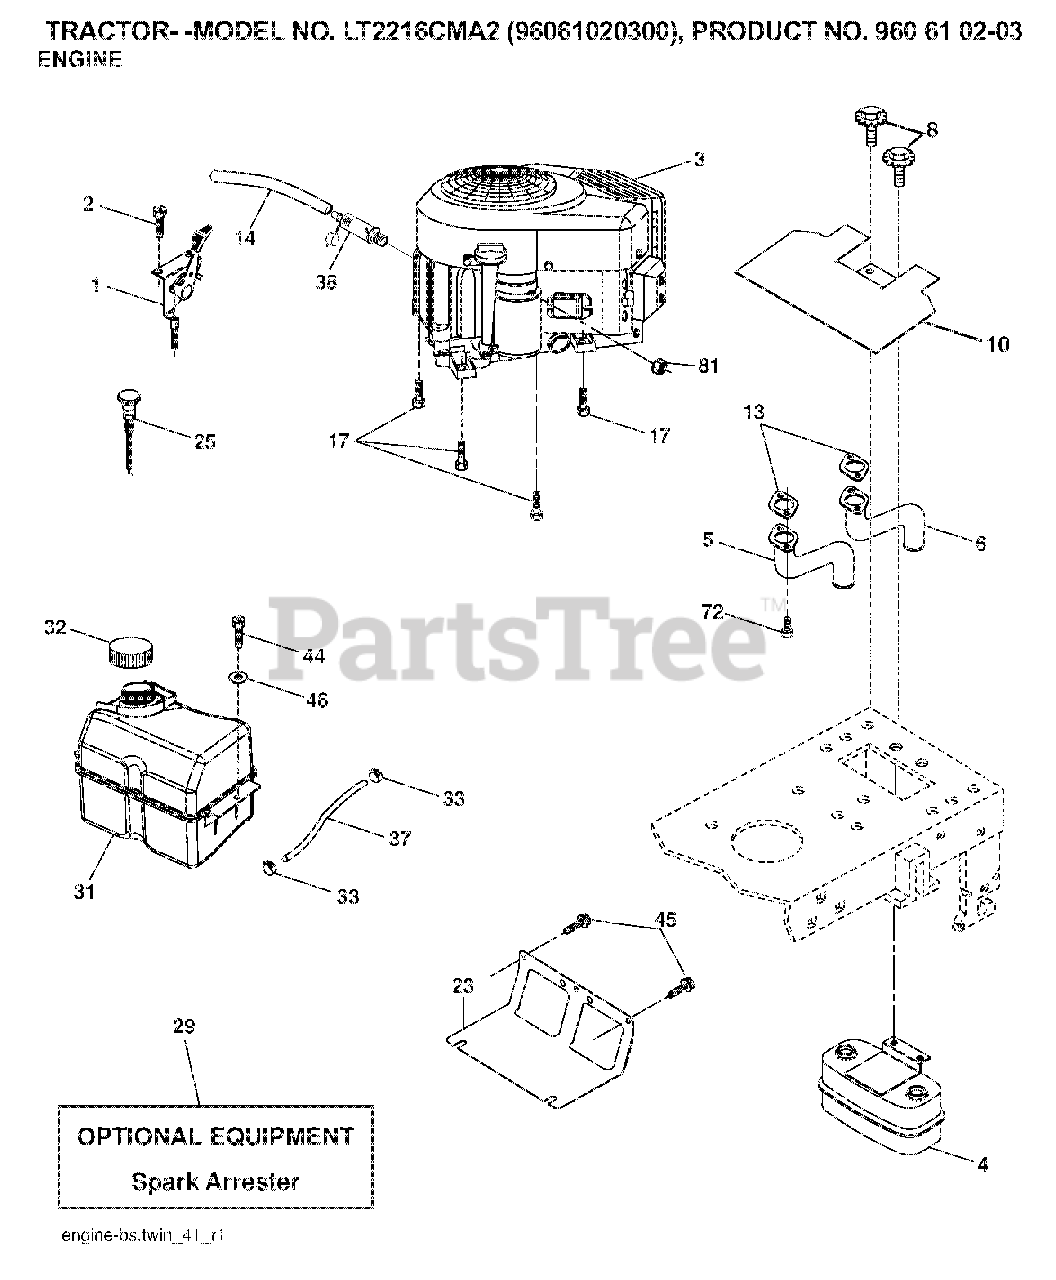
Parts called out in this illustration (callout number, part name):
1	CONTROL, THROTTLE
2	SCREW
4	MUFFLER.TWIN.CYL.LOW.TONE
5	TUBE MANIFOLD LH
6	EXHAUST TUBE RH
8	BOLT, 5/16-18 X 1 3/4
10	RP SHIELD HEAT MUFFLER
13	GASKET.MUFFLER
14	TUBE, DRAIN OIL ASM.
17	SCREW.3/8-16
23	SHEILD.BROWNING.DBR.GUARD
25	CONTROL, CHOKE, 37", PUSH
29	ARRESTER SPARK (OPTIONAL)
31	FUEL TANK FRT 2 GAL.
32	FUEL CAP
33	HOSE CLAMP
37	LINE.FUEL.20
38	PLUG DRAIN OIL EASY
44	SCREW HEXWSHR 1/4-20X3/4
45	SCREW, 3/8-16X3/4
72	SCREW.SOCKET.HEAD.5/16-18
81	NUT
